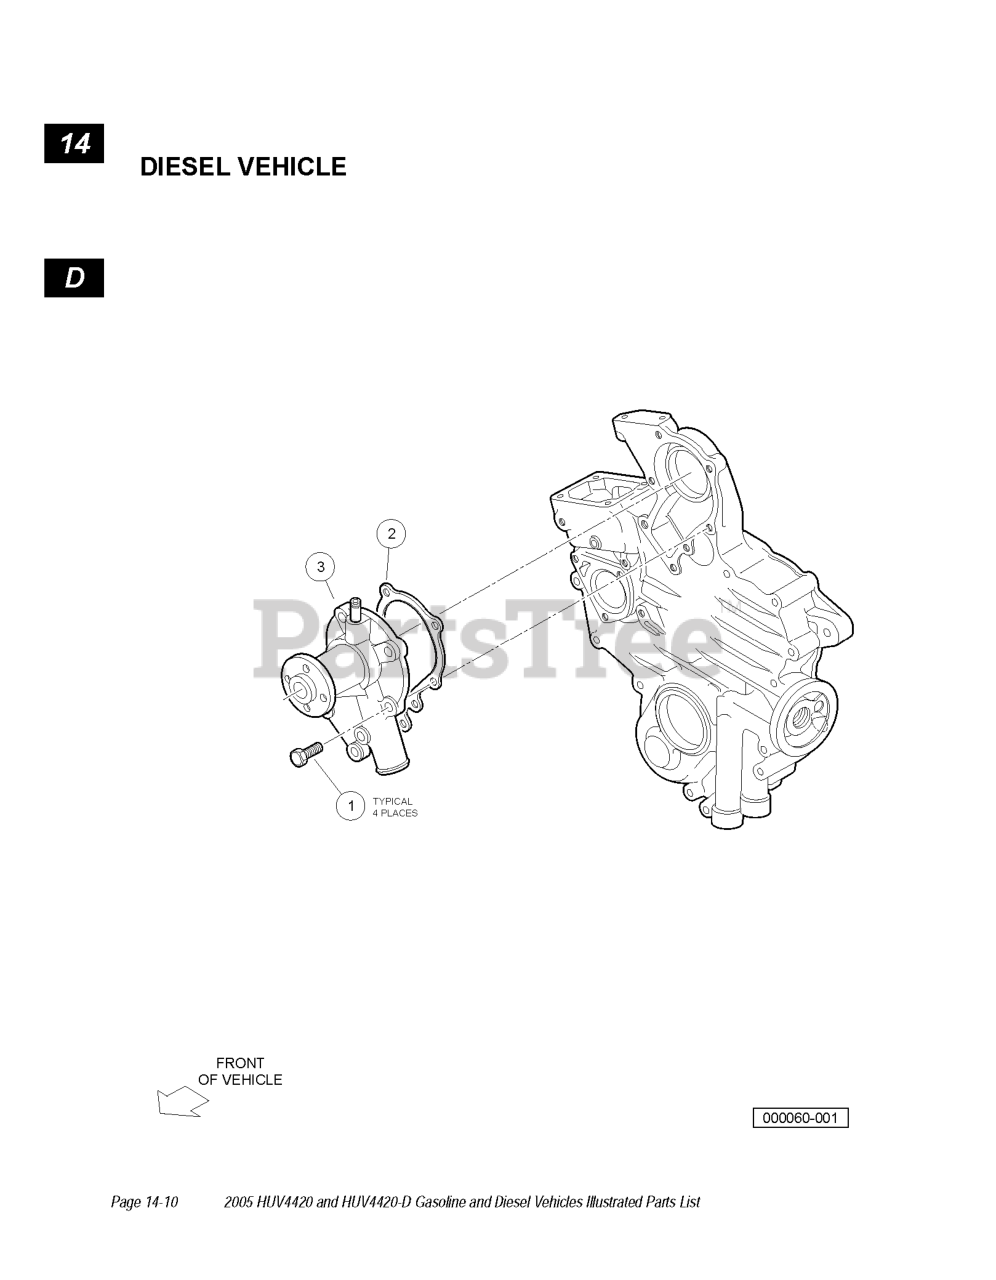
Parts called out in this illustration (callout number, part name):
1	BOLT, M6 X 1 X 22
2	GASKET, WATER PUMP, D722
3	WATER PUMP ASSEMBLY
